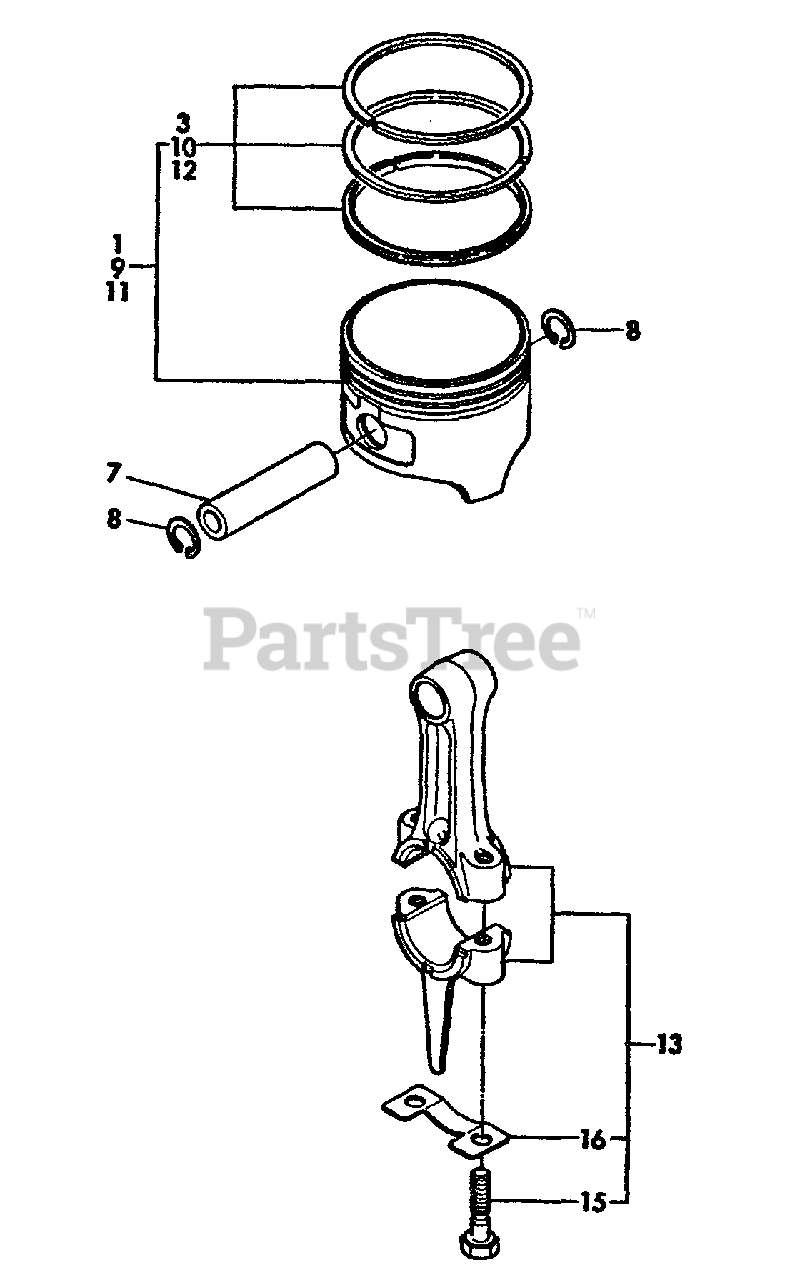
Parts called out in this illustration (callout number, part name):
1	PISTON KIT
3	RING, PISTON
7	PIN, PISTON
8	RING, RETAINING - 13
9	PISTON KIT
10	RING, PISTON
11	PISTON KIT
12	RING, PISTON
13	CONNECTING ROD ASSY
15	BOLT, ROD
16	WASHER
